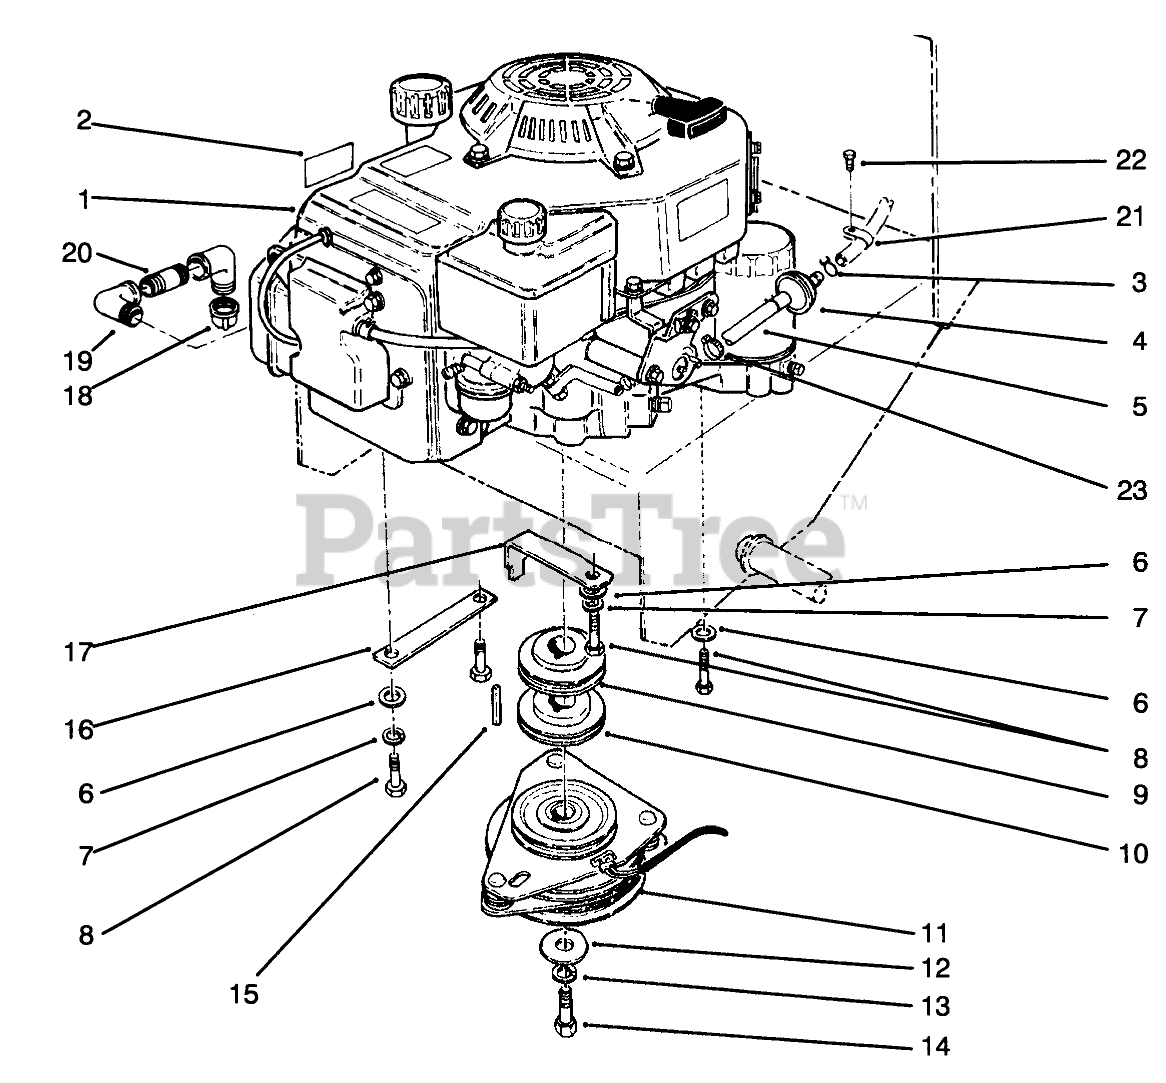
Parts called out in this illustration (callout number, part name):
2	DECAL-SURFACE, HOT
3	CLAMP-HOSE
4	FILTER-FUEL
5	HOSE-FUEL
6	WASHER-PLAIN
7	WASHER-LOCK
8	SCREW-HH
9	SHEAVE-UPPER HALF
10	SHEAVE-LOWER HALF
11	CLUTCH/BRAKE
12	WASHER-CLUTCH
13	WASHER-LOCK
14	SCREW-CLUTCH
15	KEY-SQUARE
16	Guard-Pulley
17	Retainer-Clutch
18	CAP-PIPE
19	ELBOW-STREET, 90 DEG
20	NIPPLE
21	CLAMP-CABLE
22	SCREW-HH
23	CLAMP-WORM
